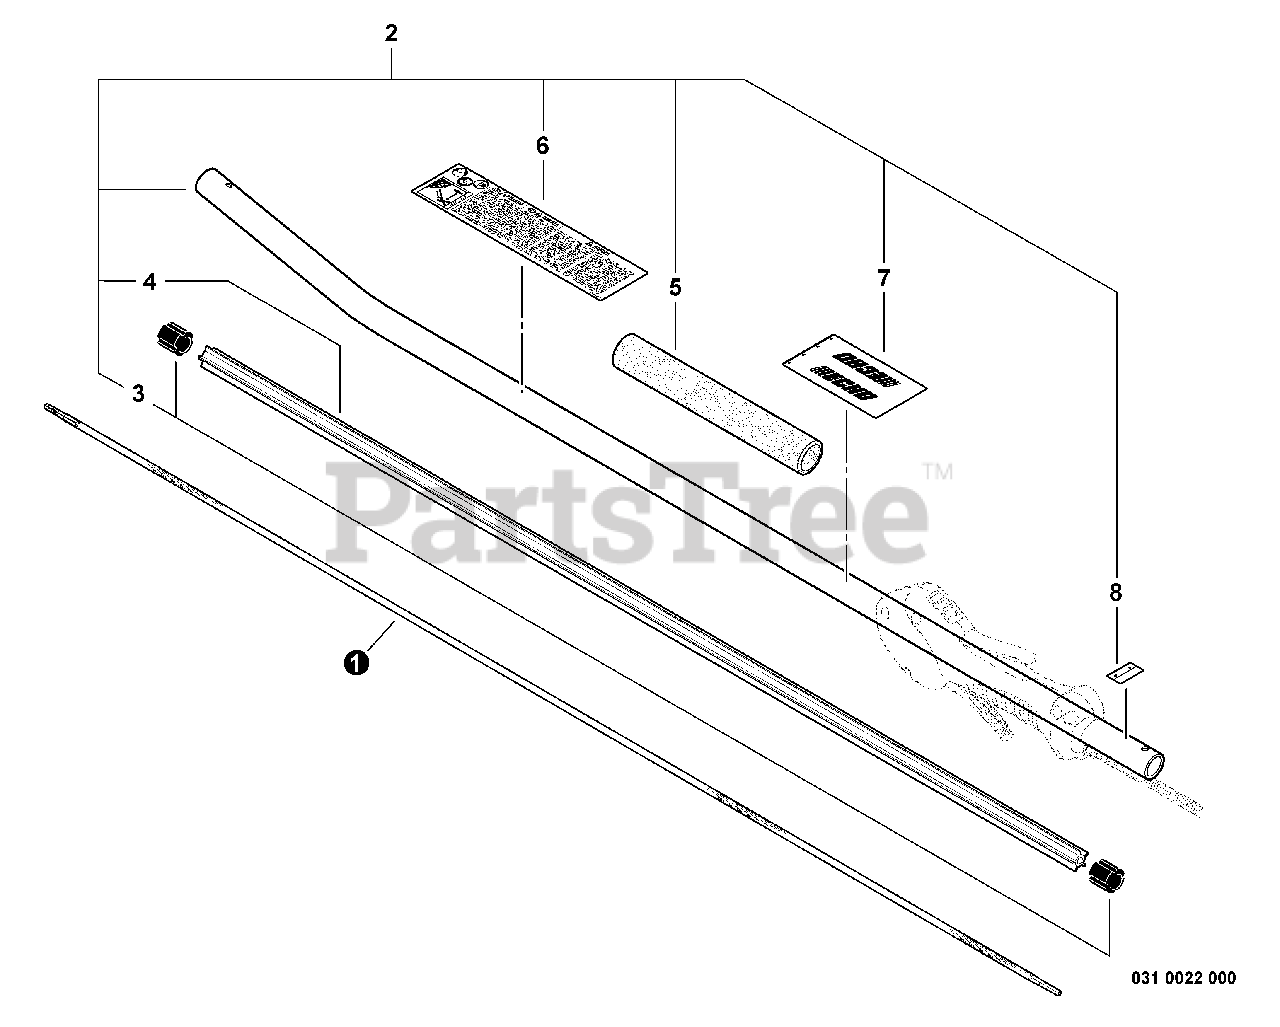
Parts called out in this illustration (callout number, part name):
1	DRIVESHAFT - FLEXIBLE
2	MAIN PIPE ASSY
4	LINER - FLEXIBLE
5	GRIP, HANDLE
6	LABEL - CAUTION
7	LABEL - HANDLE LOCATION
8	LABEL - ALIGNMENT
